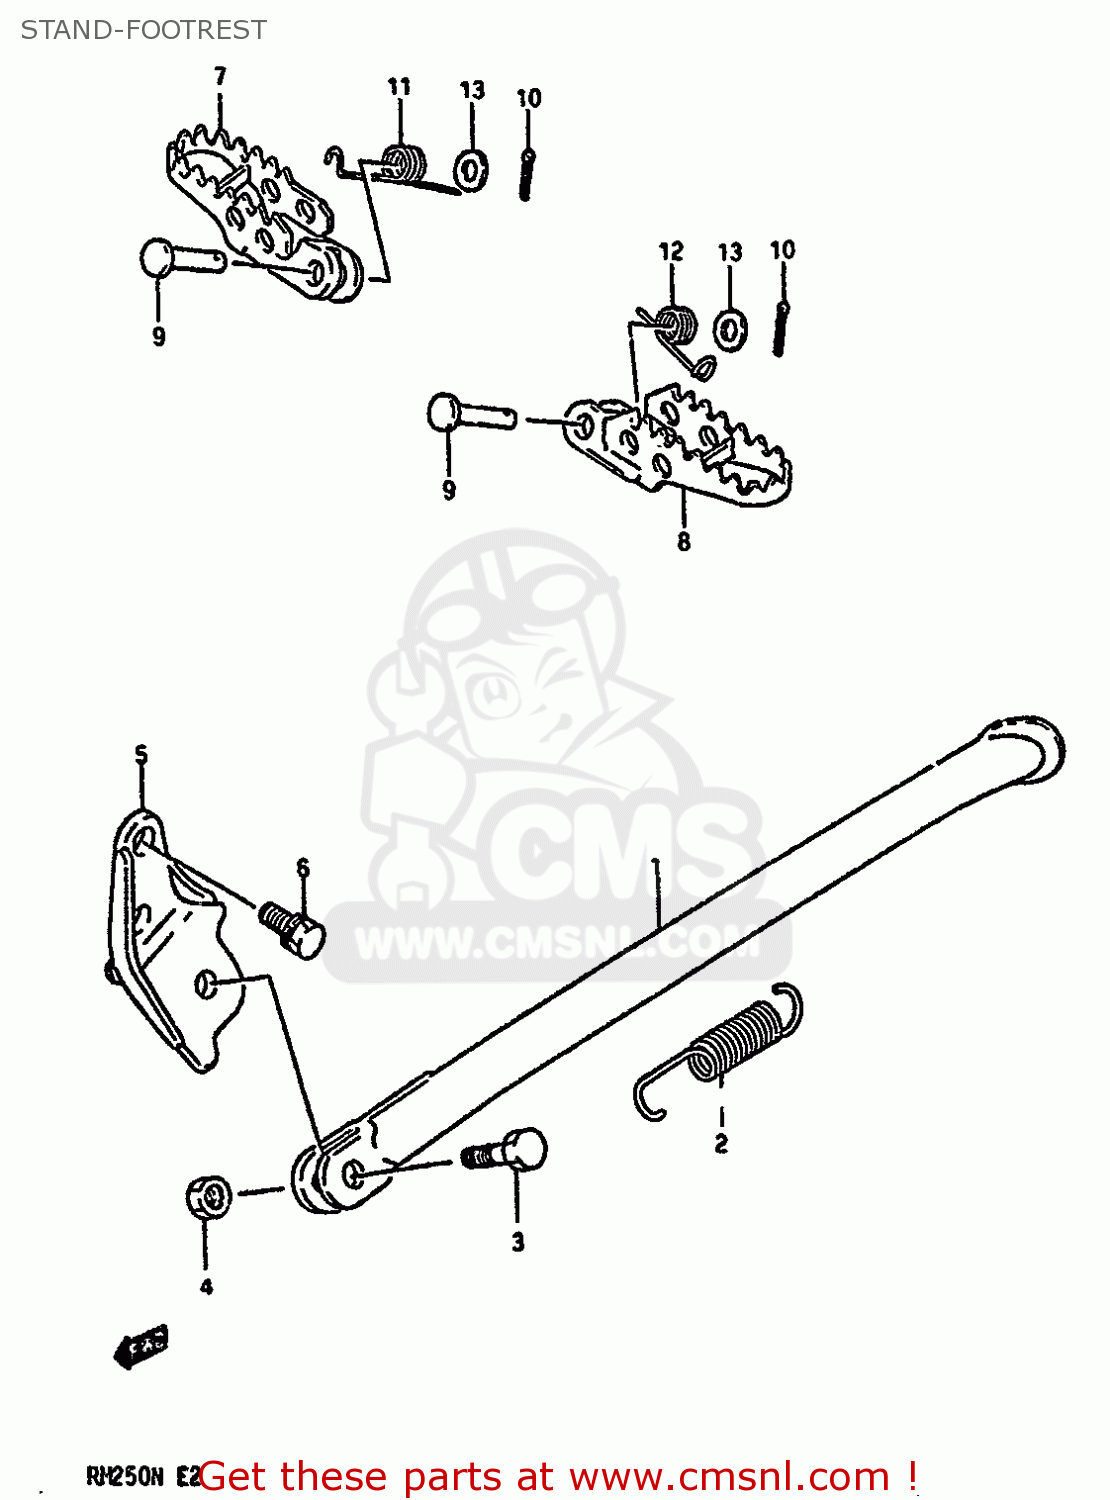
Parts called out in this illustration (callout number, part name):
1	STAND,SIDE
2	SPRING
3	BOLT(10X30)
4	NUT
5	BRACKET,SIDE STAND
6	BOLT
7	FOOTREST,FRONT,RIGHT
8	FOOTREST,FRONT,LEFT
9	PIN
10	PIN 25X20
11	SPRING
12	SPRING
13	WASHER
